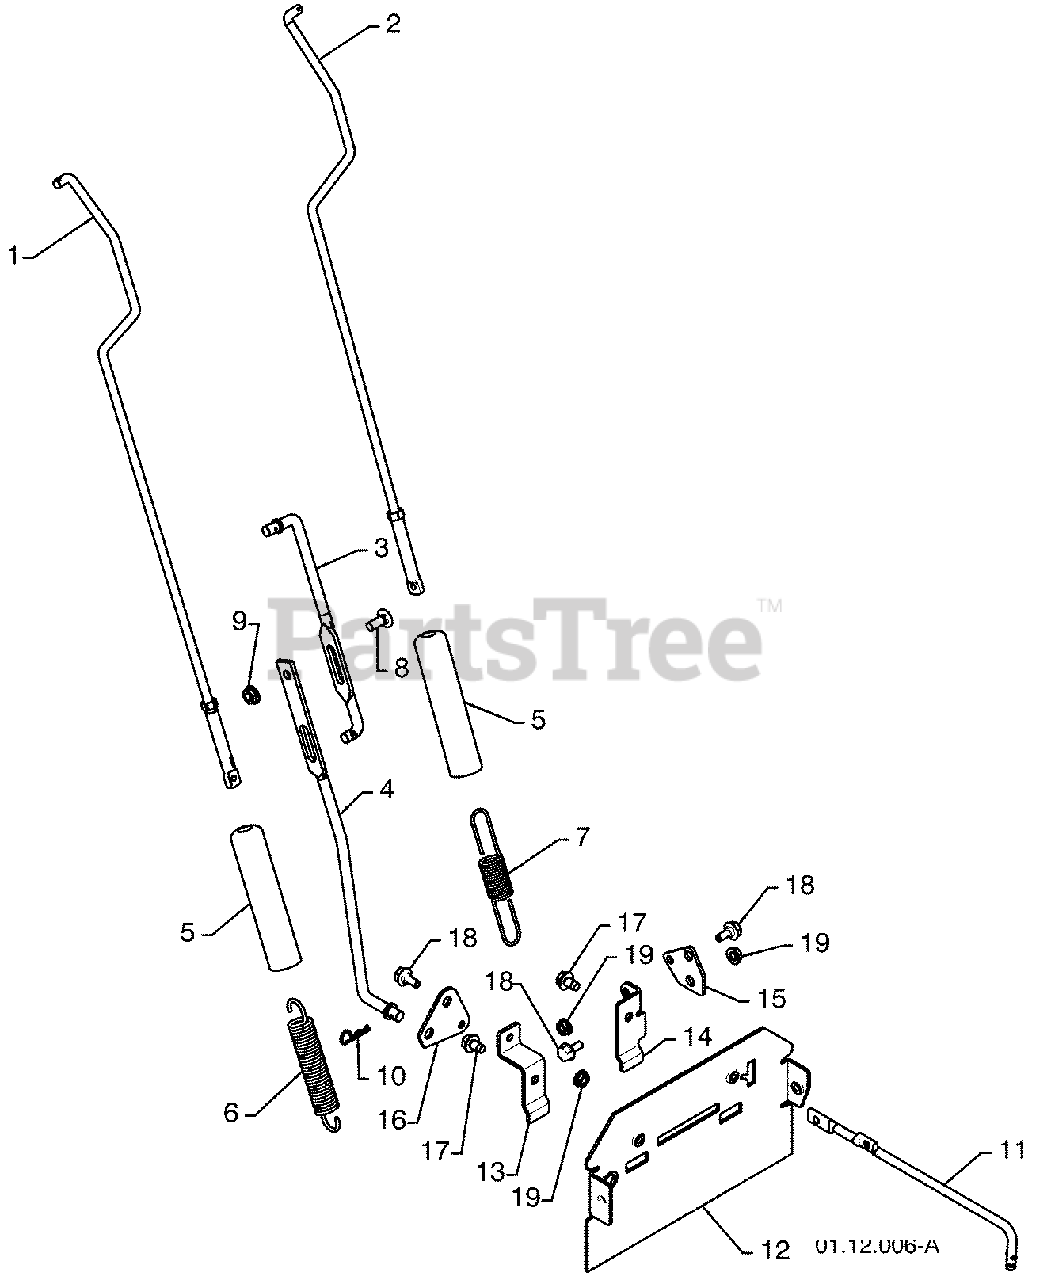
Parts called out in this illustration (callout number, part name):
1	IMPELLER ROD ASSEMBLY
2	TRACTION ROD ASSEMBLY
3	SHIFTER ROD TOP
4	SHIFTER ROD BOTTOM
5	SPRING SLEEVE
6	IMPELLER SPRING
7	TRACTION SPRING
8	CARRIAGE BOLT 5/16-18 X .750
9	NUT 5/16-18
11	CLUTCH ROD
12	REAR PLATE
13	SHIFTER PLATE BRACKET
14	CLUTCH PLATE BRACKET
15	CLUTCH PLATE
16	SHIFTER PLATE
17	BOLT 5/16-18 X .500
18	SHOULDER BOLT 1/4-20 X .500
19	NUT 1/4-20
